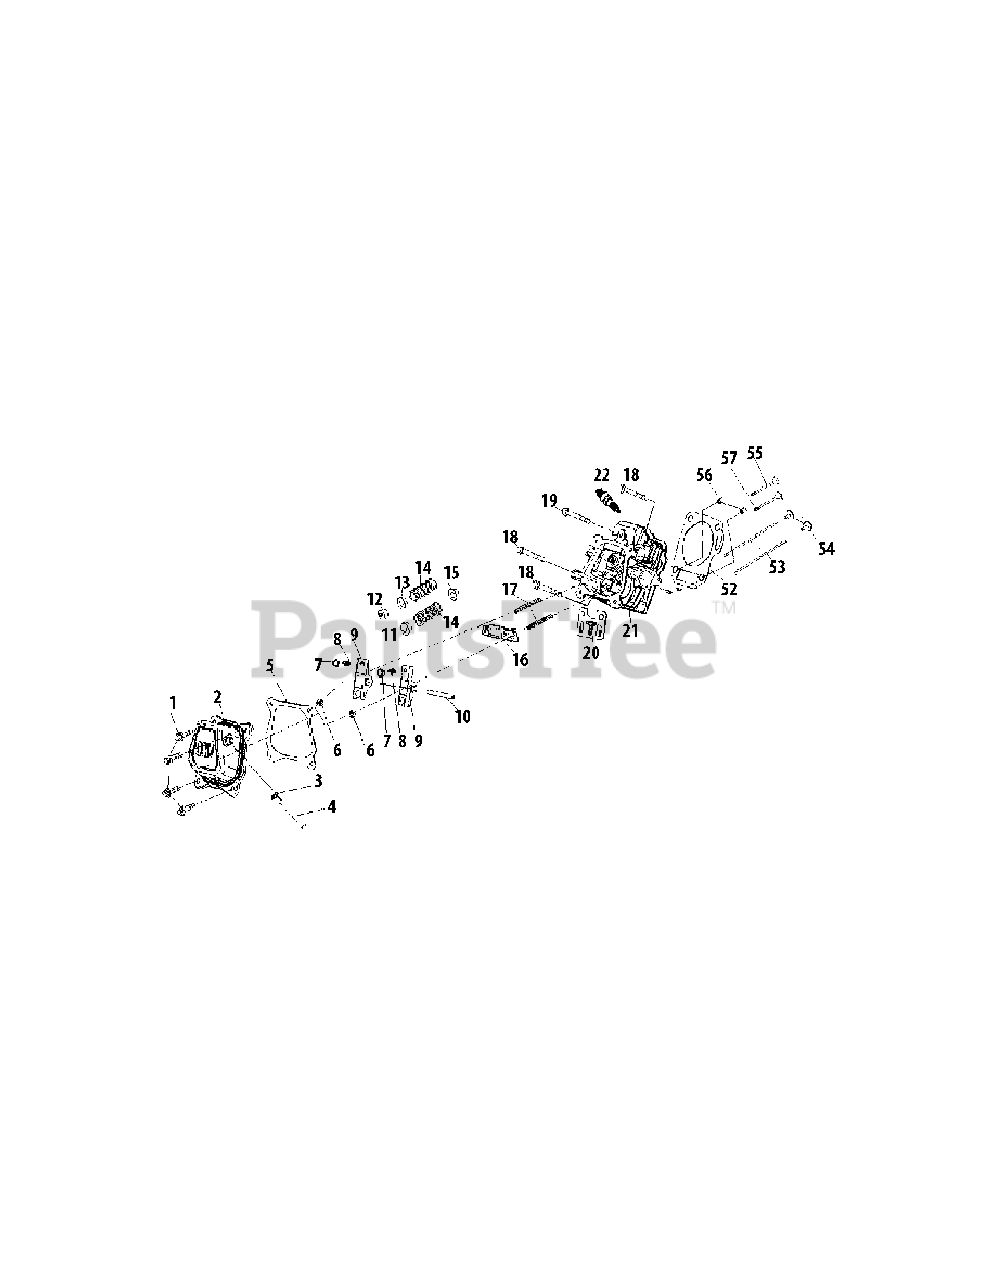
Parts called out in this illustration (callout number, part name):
1	Bolt, M6×16
2	Valve Cover
4	Breather Hose
5	Gasket, Valve Cover
7	Adjust Nut
8	Adjust Nut
9	Rocker Arm
10	Rocker Arm Shaft
11	Valve Spring Seat
12	Valve Adjust Cap, Exhaust
13	Valve Spring Seat
14	Valve Spring
15	Intake Valve Seal
16	Rocker Arm Seat
18	Bolt, M10×1.25×65
19	Bolt, M10×1.25×70
20	Rocker Arm Base
21	Cylinder Head
22	Spark Plug
52	Gasket, Cylinder Head
53	Push Rod
55	Pin, 12×16
56	Intake Vavle
57	Exhaust Valve
